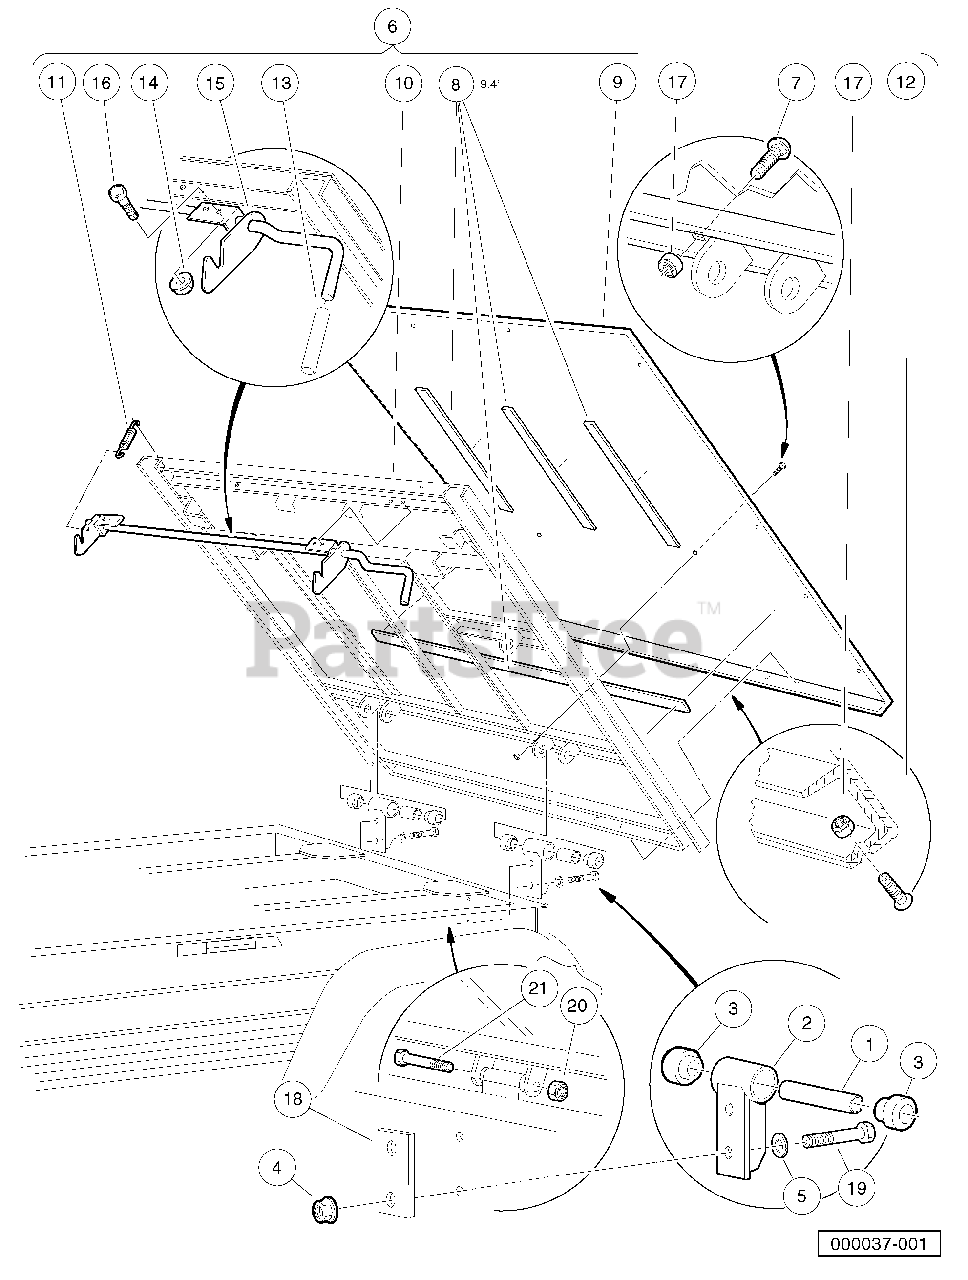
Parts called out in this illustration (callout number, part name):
1	Bushing, Steel
3	Bushing, Urethane
4	Locknut, 3/8-16 Flanged Dimple
5	Washer, 3/8 Type B Hard Flat
6	Tilt Bed Assembly
7	Bolt, Carriage, 5/16-18 X 1.00
8	Tape, Vinyl Foam 1/8" x 3/4"
9	Plate, Floor Bed
10	Frame Assembly
11	Extension, Spring Latch
12	Screw, 5/16-18 X 0.88 Torx Truss-Head
13	Grip, Tilt Latch Hand
14	Locknut, 1/4-20 Hex Whiz
15	Ltch Weld Asm Tlt Bd
16	Screw, 1/4-20 X 0.625 Hex-Head Cap
17	Locknut, 5/16-18 Nylon Insert
18	Plate, Back
19	Bolt, 3/8-16 X 3.00 Hex Head
20	Locknut, 3/8-16 Hex
21	Screw, 3/8-16 X 3.375 Hex Cap
